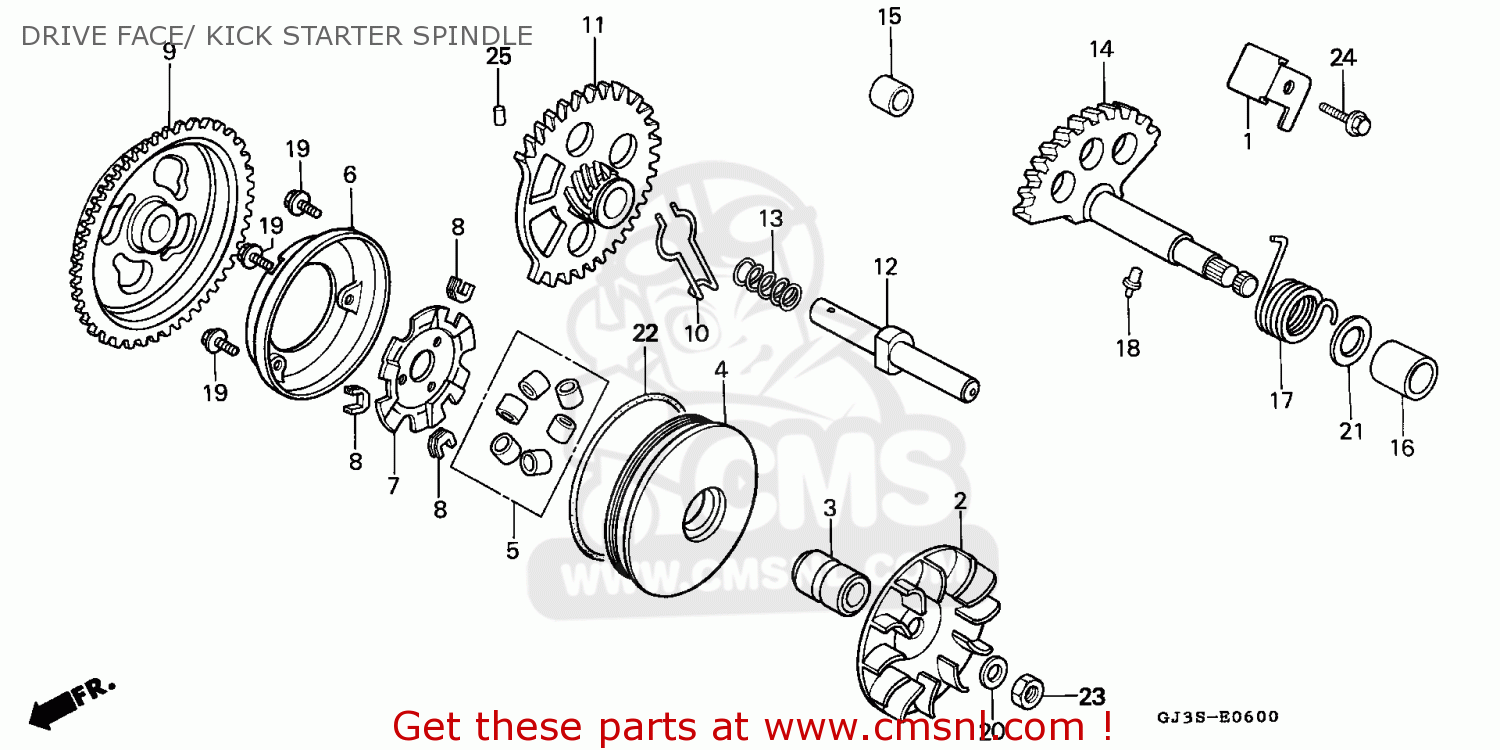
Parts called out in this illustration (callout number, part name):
1	PL,KICK RET.STOP.
2	FACE,DRIVE
3	BOSS,DRIVE FACE
4	FACE,MOVABLE DRIV
5	ROLLER SET,WEIGHT
6	SEAL,MOVABLE FACE
7	PLATE,RAMP
8	PIECE,SLIDE SET
9	GEAR,KICK STARTER
10	SPG,START GEAR
11	GEAR,START.IDLE
12	SHAFT,START,IDLE
13	SPG,START IDLE
14	SPDL,KICK.STARTER
15	BUSH,12X16X12
16	BUSH B,KICK SPDL
17	SPG,KICK STARTER
18	PIN,SPECIAL,4.5MM
19	BOLT,FLANGE 4X10
20	WASHER,SPECIAL,10
21	WASHER,THRUST 14
22	O-RING,87.2X2.6
23	NUT.HEX 10MM
24	BOLT,FLANGE,SH,6X16
25	ROLLER 3X8.5
